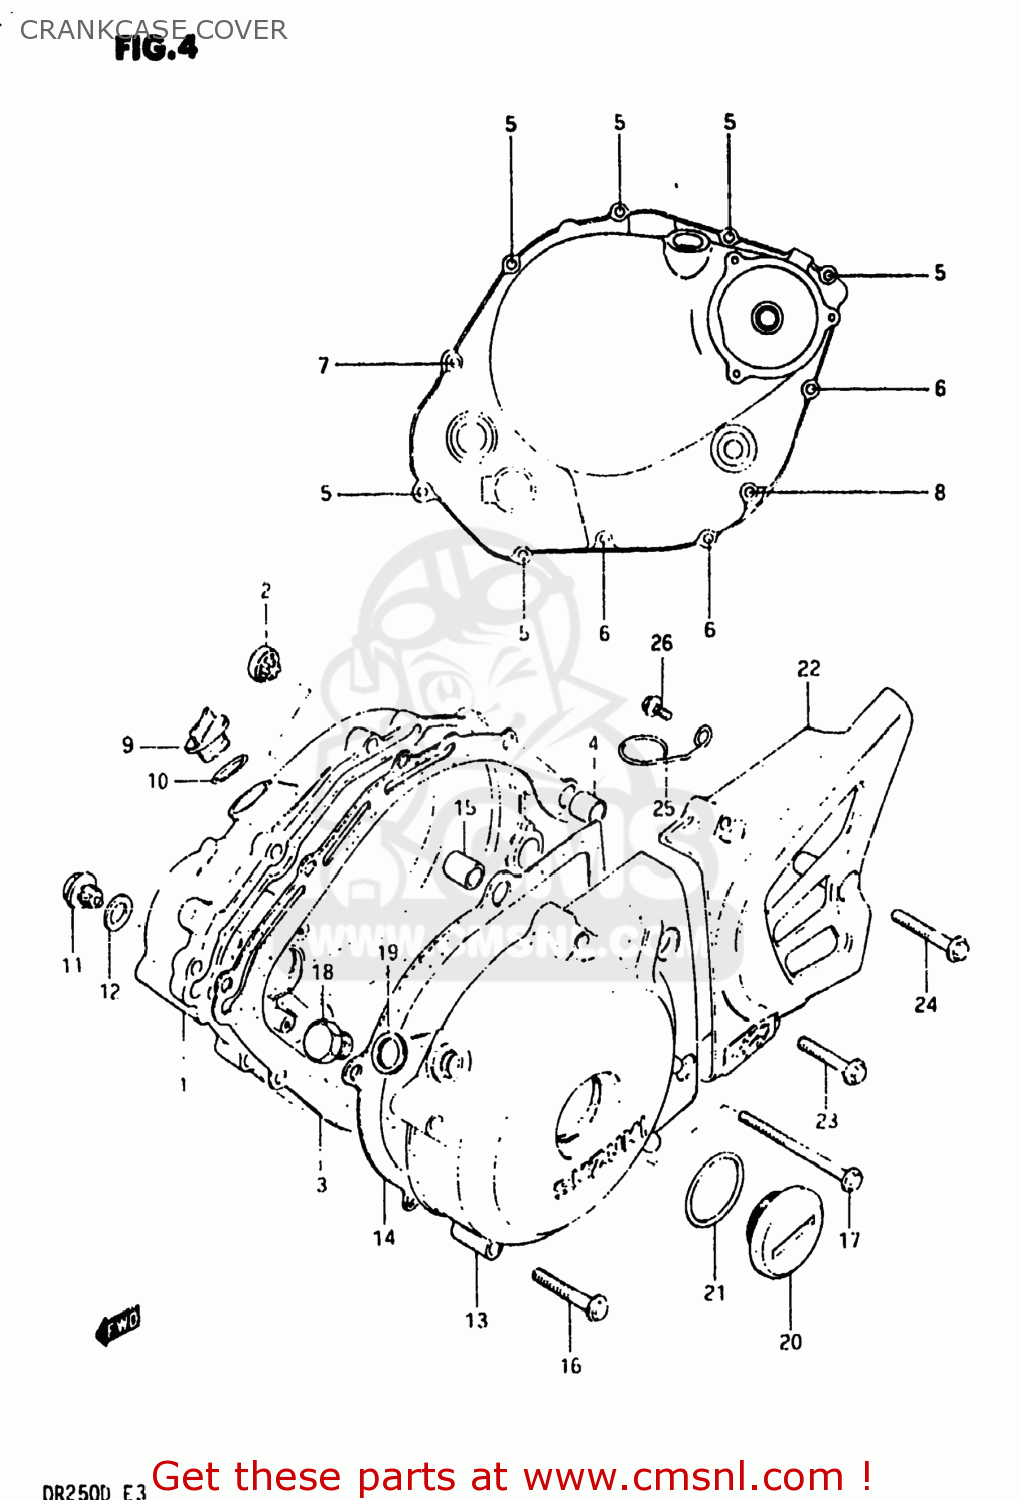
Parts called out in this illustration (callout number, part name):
1	COVER,CLUTCH
2	LENS,OIL LEVEL CHECK
3	GASKET,CLUTCH COVER (MCA)
4	PIN
5	BOLT (6X25)
6	BOLT (6X35)
7	BOLT (6X40)
8	BOLT (6X45)
9	PLUG
10	O RING(D:3.1,ID:16.8)
11	PLUG (14X12)
12	GASKET(14X19.2X2) (NAS)
13	COVER
14	GASKET,MAGNETO COVER (MCA)
15	PIN
16	BOLT (6X35)
17	BOLT 6X50
18	PLUG(12X9)
19	GASKET(12.1X16.2X3.7) (NAS)
20	PLUG
21	O RING(D:3.1,ID:32.7)
22	COVER,SPROCKET
23	SCREW
24	SCREW
25	GUIDE
26	BOLT
